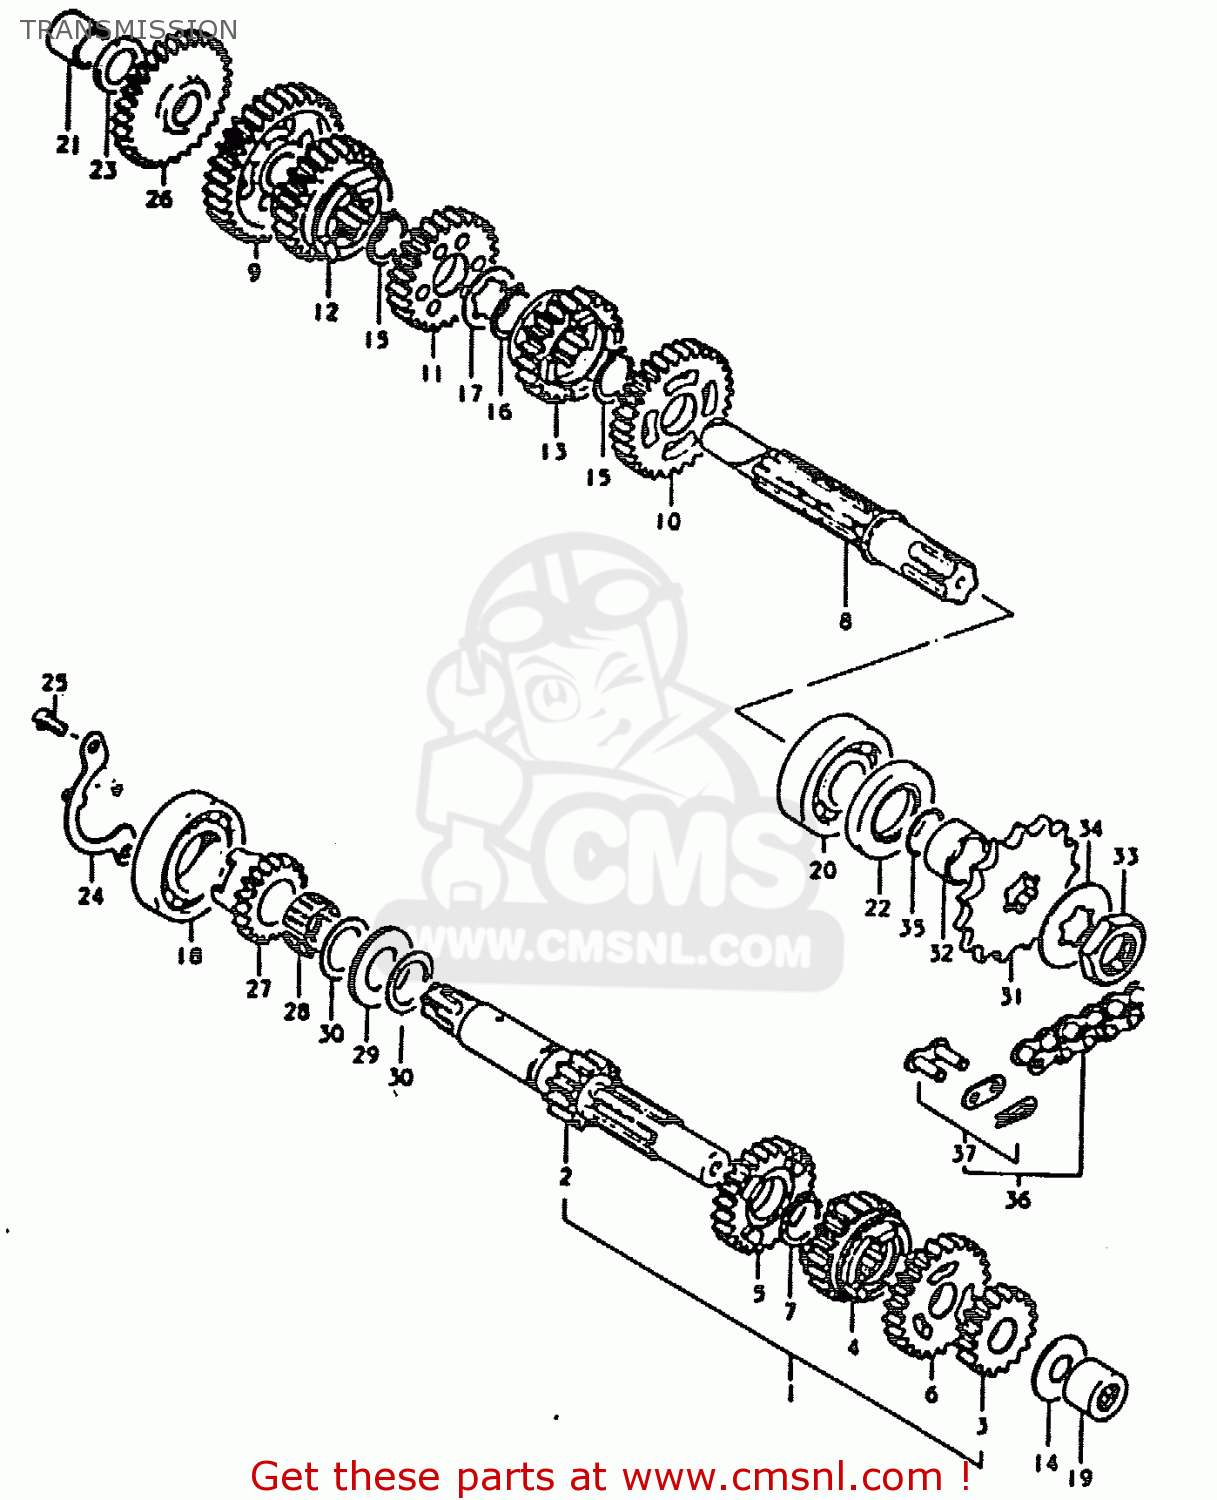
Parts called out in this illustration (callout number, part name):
1	SHAFT,COUNTER
2	SHAFT,COUNTER
3	GEAR,2ND DRIVE
4	GEAR,3RD DRIVE
5	GEAR,FOURTH DRIVE
6	GEAR,5TH DRIVE
7	CIRCLIP
8	SHAFT,DRIVE
9	GEAR,1ST DRIVEN
10	GEAR,2ND DRIVEN
11	GEAR,THIRD DRIVEN
12	GEAR,FOURTH DRIVEN
13	GEAR,FIFTH DRIVEN
14	WASHER
15	CIRCLIP
16	CIRCLIP
17	WASHER
18	BEARING, RH
19	BEARING(15X22X15)
20	BEARING
21	BUSH
22	OIL SEAL (25X44X7)
23	WASHER
24	RETAINER,CNTR SHAFT BEARING
25	SCREW 6X12
26	GEAR,KICK STARTER IDLE
27	GEAR,KICK STARTER DRIVEN
28	BEARING(19.2X23.2X19)
29	BEARING(21X32X2.85)
30	WASHER(21X30X0.8)
31	SPROCKET,ENGINE
32	SPACER(20X25X12.5)
33	NUT
34	WASHER,LOCK
35	O RING(D:1,ID:19.5)
36	CHAIN ASSEMBLY,DRIVE
37	JOINT
